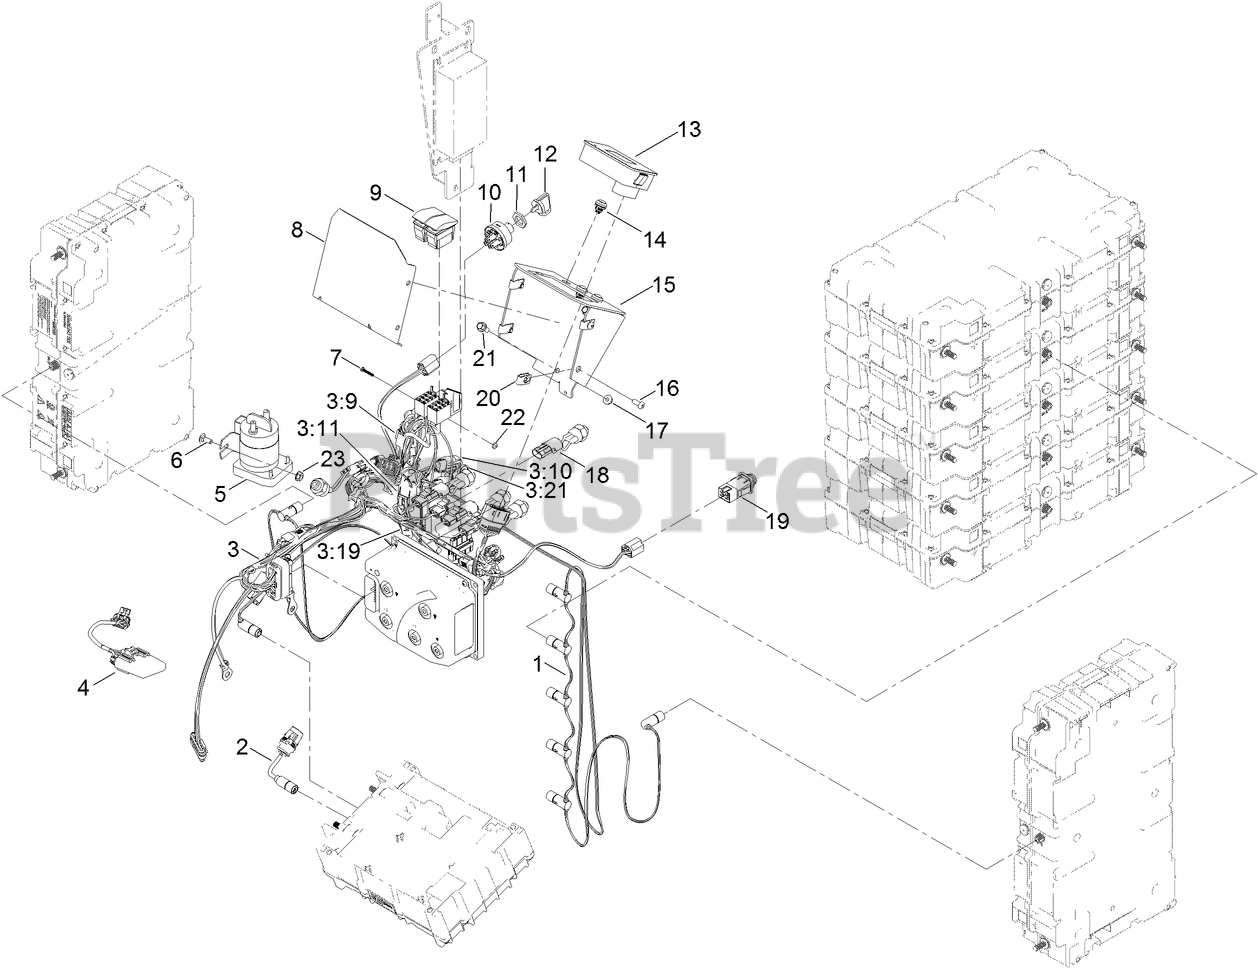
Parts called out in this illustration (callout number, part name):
1	HARNESS-WIRE, SAMSUNG INTERFACE M/S
2	HARNESS-WIRE, INTERFACE (SYSTEM)
3	HARNESS-WIRE, MAIN
3:9	RESISTOR-120 OHM
3:10	CAP-PLUG, 3 WAY
3:11	COVER-FUSE, SINGLE
3:19	CAP-PLUG
3:21	MOUNT-TIE WRAP, MAGNETIC
4	ISOLATED CAN MODULE ASM
5	CONTACTOR-TROMBETTA
6	SCREW-CARR
8	COVER-DISPLAY
9	SWITCH-ROCKER, OFF-NONE-ON
10	SWITCH-KEY, SPST
12	KEY-IGNITION
13	TDM 2002
14	SWITCH-PUSHBUTTON
15	MOUNT-DISPLAY
16	SCREW-HSBH
17	NUT-HF
18	SWITCH-BALL
19	SWITCH-PLUNGER
21	SCREW-HEAD, FLANGE
22	NUT-HEX
23	NUT-HF
